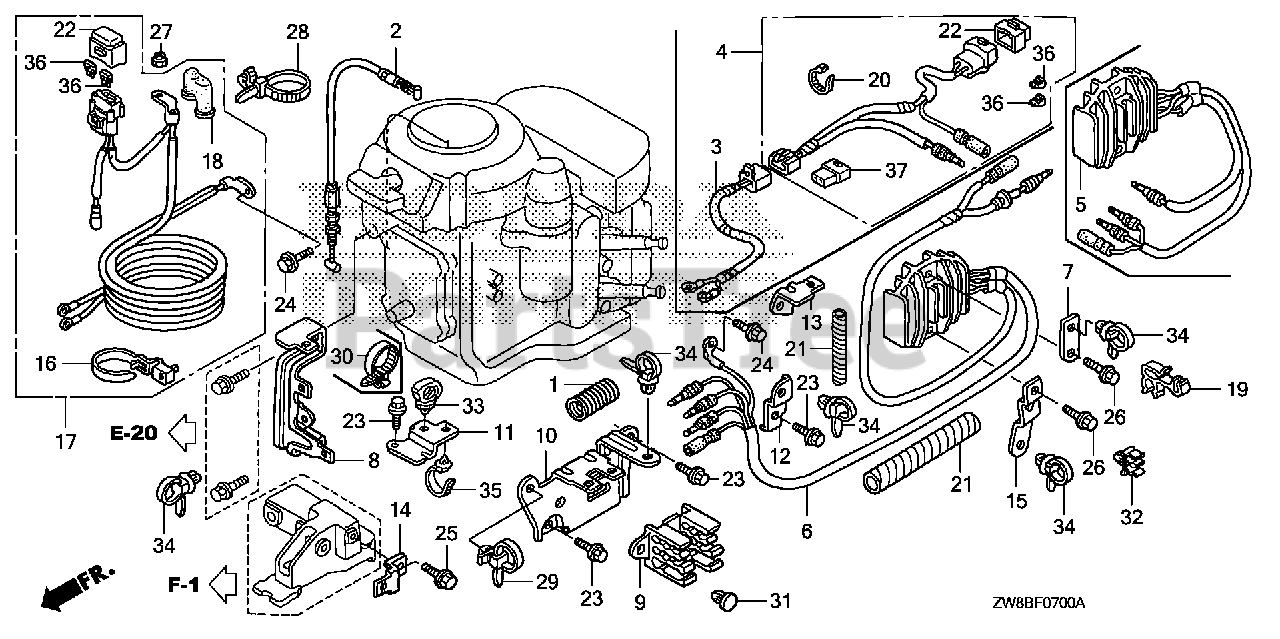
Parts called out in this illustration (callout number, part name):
2	CABLE, NEUTRAL STARTING
3	WIRE ASSY., BATTERY CHARGE
4	RECEPTACLE ASSY., CHARGE
5	RECTIFIER ASSY., REGULATOR
7	BRACKET, CLIP F
8	BRACKET, CONNECTOR (A)
9	BRACKET, CONNECTOR (B)
10	BRACKET, CONNECTOR (C)
11	BRACKET, STARTER CABLE
12	BRACKET, CLIP B
13	BRACKET, FUSE CASE
14	BRACKET, CONNECTOR (D)
15	BRACKET, E-CLIP
19	CLAMP, DISTRIBUTOR WIRE
20	TIE, CABLE (NATURAL 2.4X92) Use up to Frame SN 1300359.
21	TUBE, SPIRAL A
22	COVER ASSY., FUSE (20A)
23	BOLT, FLANGE (6X14) (CT200)
25	BOLT, FLANGE (6X12) Use from Frame SN 1005249.
26	BOLT, FLANGE (6X26) (CT200)
29	STRAP, CABLE (118MM) *NH1L* (Honda Code 1170653). (BLACK)
31	CLIP, ANCHOR
32	CLIP, FUEL TUBE
33	CLIP, HARNESS
34	CLIP, HARNESS BAND (151.5MM) (NATURAL)
36	FUSE, BLADE (20A)
37	CONNECTOR, DUMMY
